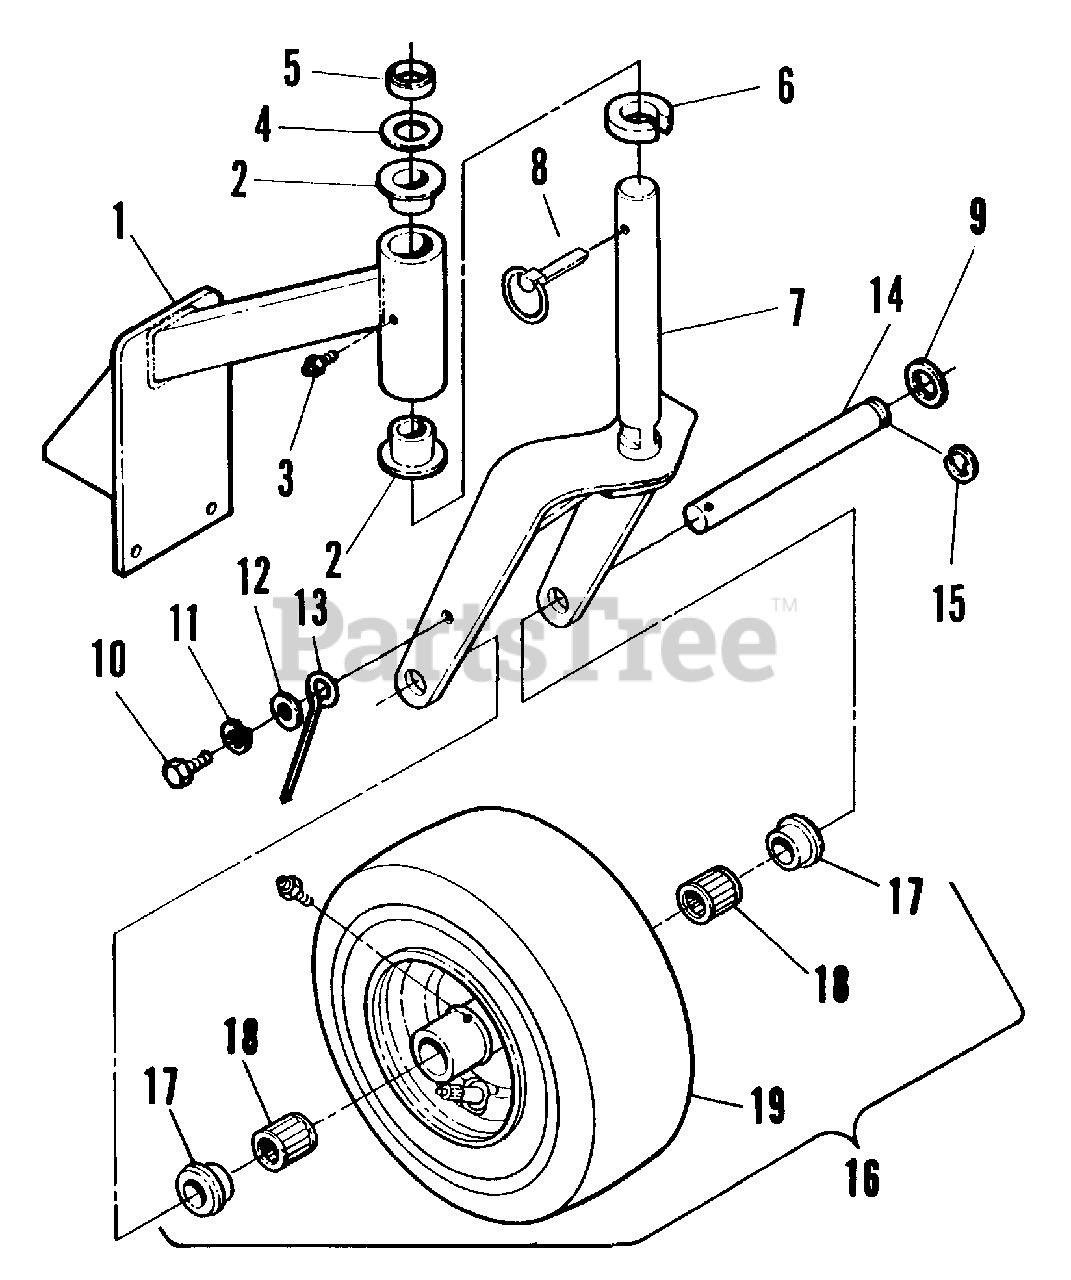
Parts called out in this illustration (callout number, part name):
1	SUPPORT, Caster (36" Deck Only)
1	SUPPORT, Caster (48", 52" & 61" Decks)
2	BUSHING, Flange
3	ZERK, 1/8" NPT Straight
4	BUSHING, Machinery, 1"
5	SPACER, 1" x 1 3/8 x .30" (PM)
6	SPACER, Caster
7	YOKE, Caster
8	PIN, Lynch 7/16
9	BUSHING, Machinery, 3/4"
10	SCREW, Hex Cap
11	LOCKWASHER, 3/8"
12	FLATWASHER, 3/8"
13	MOUNT, Caster Axle
14	AXLE, Caster
16	WHEEL & TIRE ASSEMBLY
17	BEARING, Flange, 3/4"
18	ROLLER BEARING, 3/4" x 1"
19	TIRE, 4-Ply Smooth Tread
